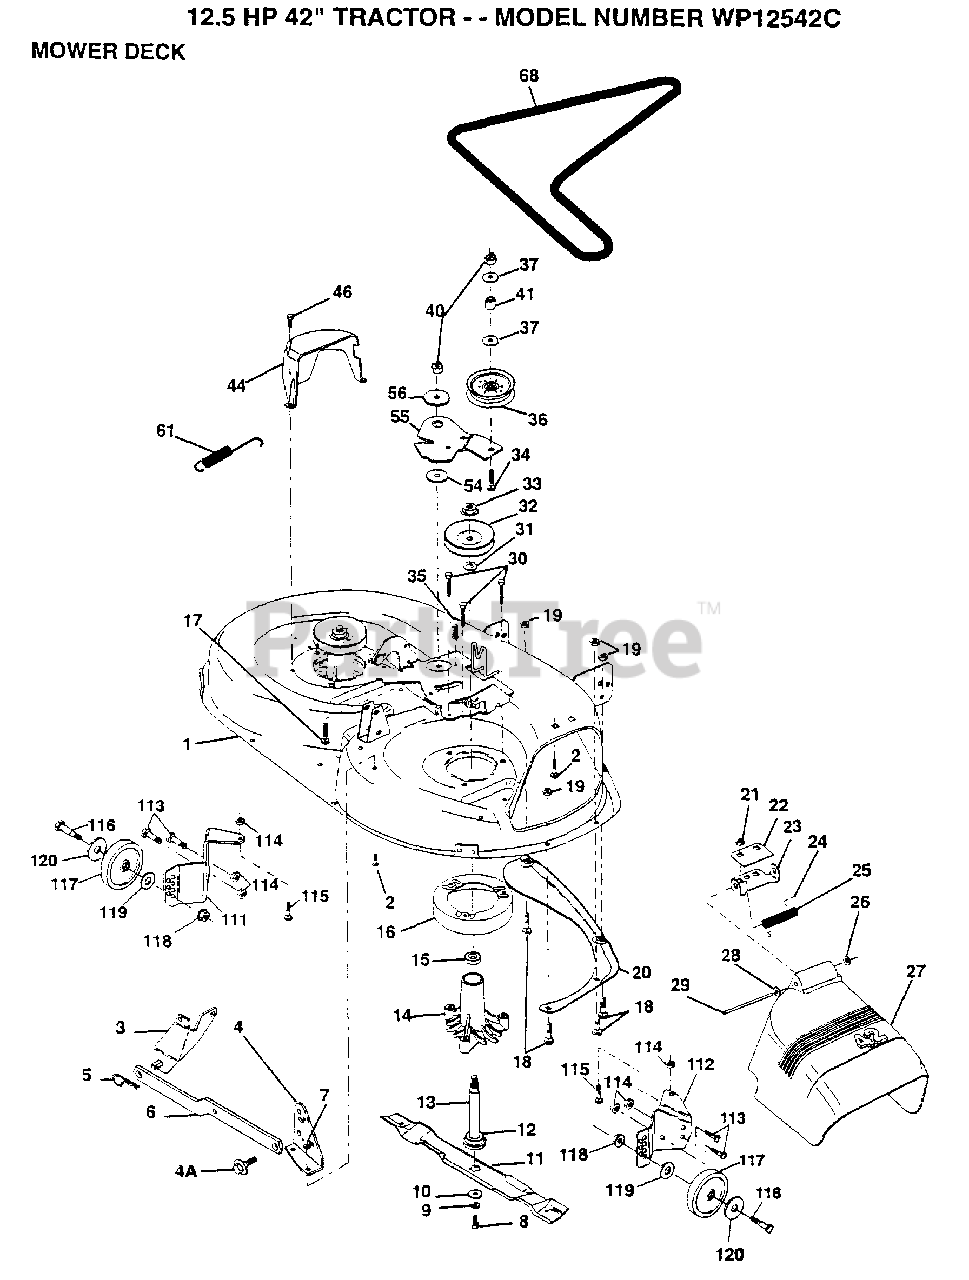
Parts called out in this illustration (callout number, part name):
2	BOLT
3	BRKT ASM SWAY BAR
4	BRKT DECK SW BAR
4A	BOLT SHD 5/16-18
7	NUT LK HEX W/INS 5/16-18 UNC P
8	BLADE BOLT
10	WASHER.HARD.BLADE
11	"BLADE.42"" MULCHER"
12	BEARING.BALL
14	HSG ASM MANDREL
15	BEARING
17	BOLT
18	BOLT
19	NUT
21	NUT
22	STIFFENER BRKT
23	DEFLECTOR BRKT
24	CAP-SLEEVE LT
25	SPRING TORSION
26	NUT PUSH M
27	DEFLECTOR.SHIELD
28	WASHER
29	HINGE ROD
31	WASHER
34	BOLT RDHD 3/8-16
35	XMAS TREE FASTNER
36	FLAT IDLER PULLEY
37	WASHER
40	NUT
44	GUARD MAND LH BLK
46	SCREW.1/4-20X5/8
54	HARDENED WASHER
56	SPACER RETAINER
61	SPRING.EXTENSION
68	BELT-V MWR 82.625
113	BOLT
116	BOLT M
117	WHEEL.GAGE.BLK.PL
118	LOCKNUT
119	WASHER
120	WASHER
